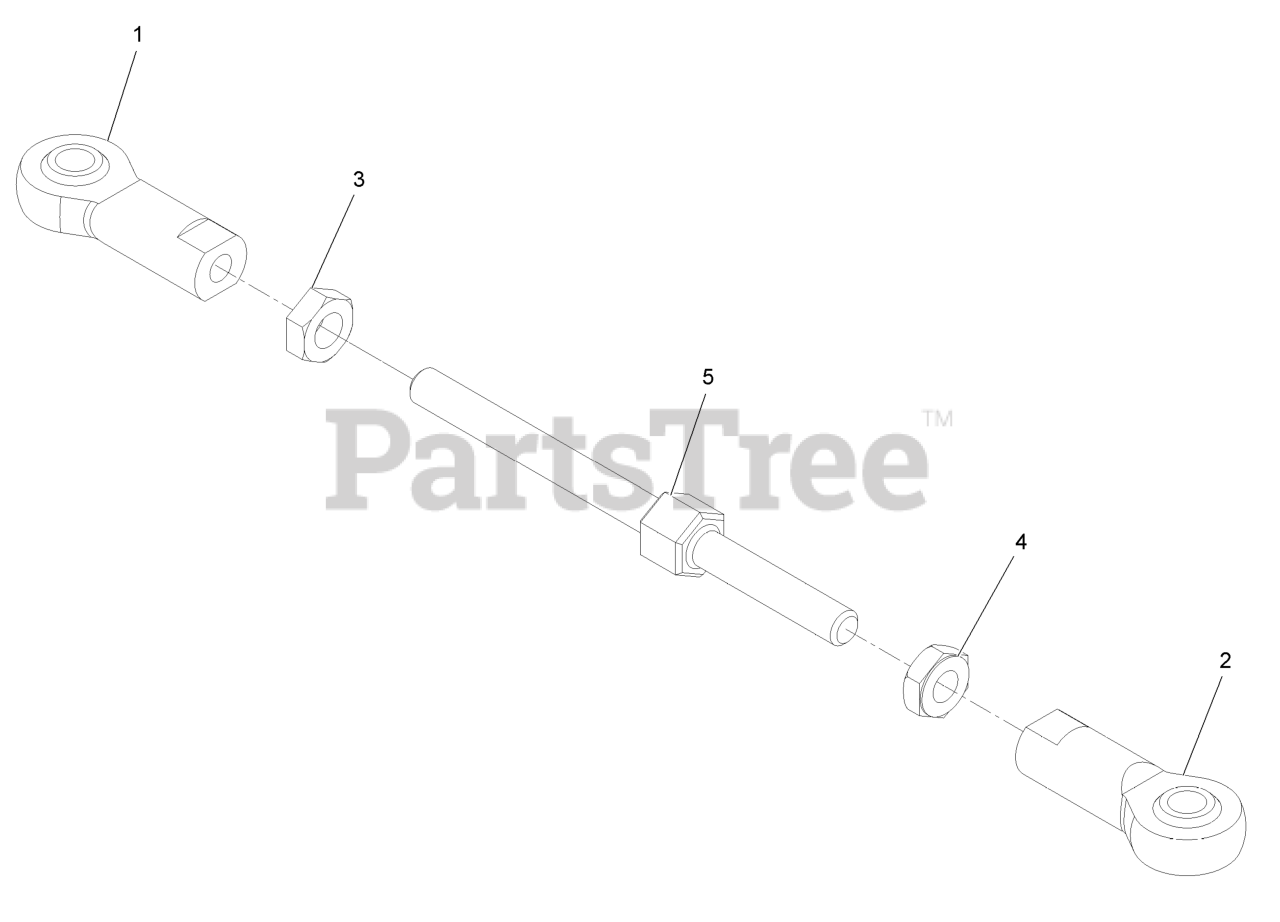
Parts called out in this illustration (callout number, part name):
1	ROD END-BALL JOINT
2	JOINT-BALL, LH
3	NUT-JAM
4	NUT-JAM
5	ROD-VERTICAL ADJUST
